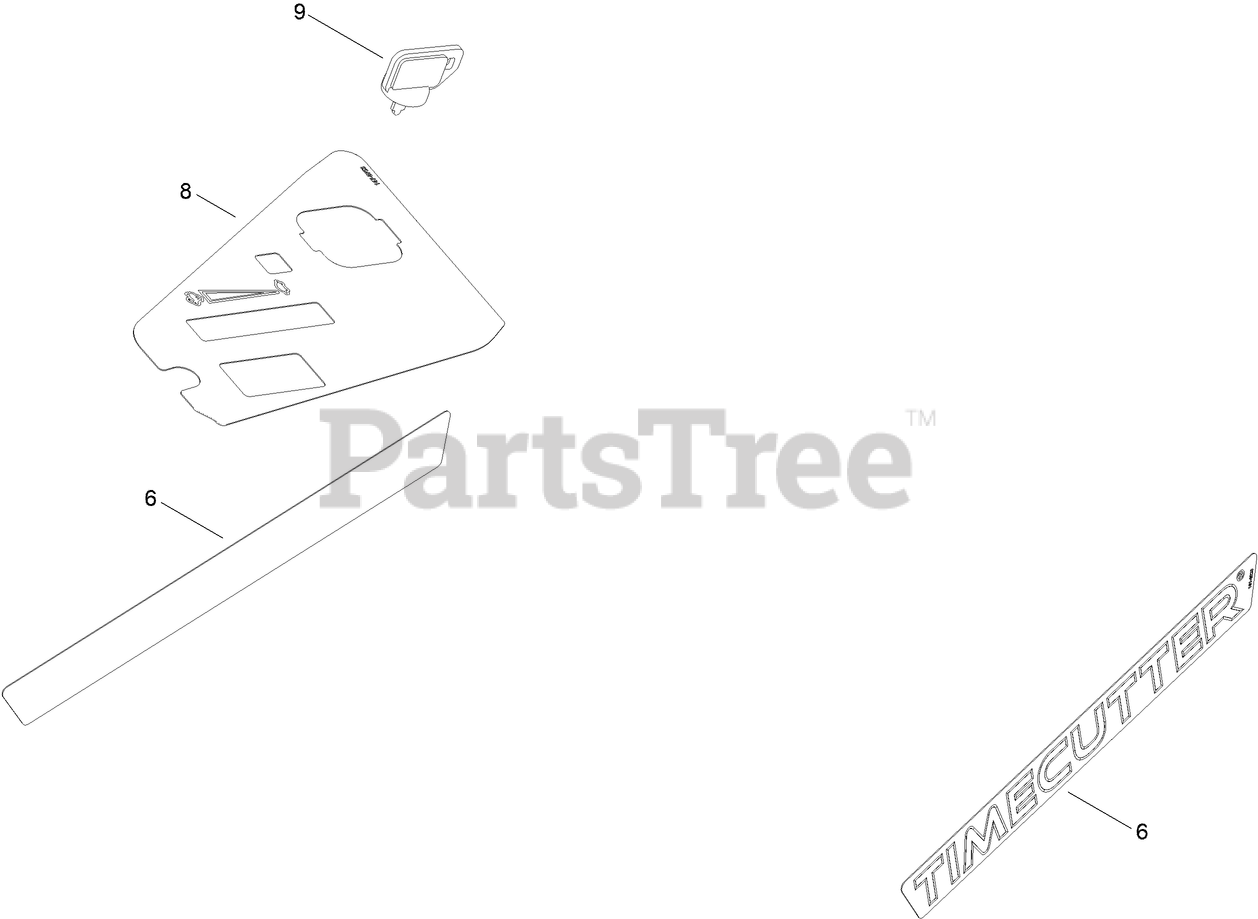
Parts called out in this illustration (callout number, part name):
6	DECAL - TIMECUTTER
8	DECAL - CONTROL PANEL W/OUT HOUR METER
9	KEY-IGNITION
